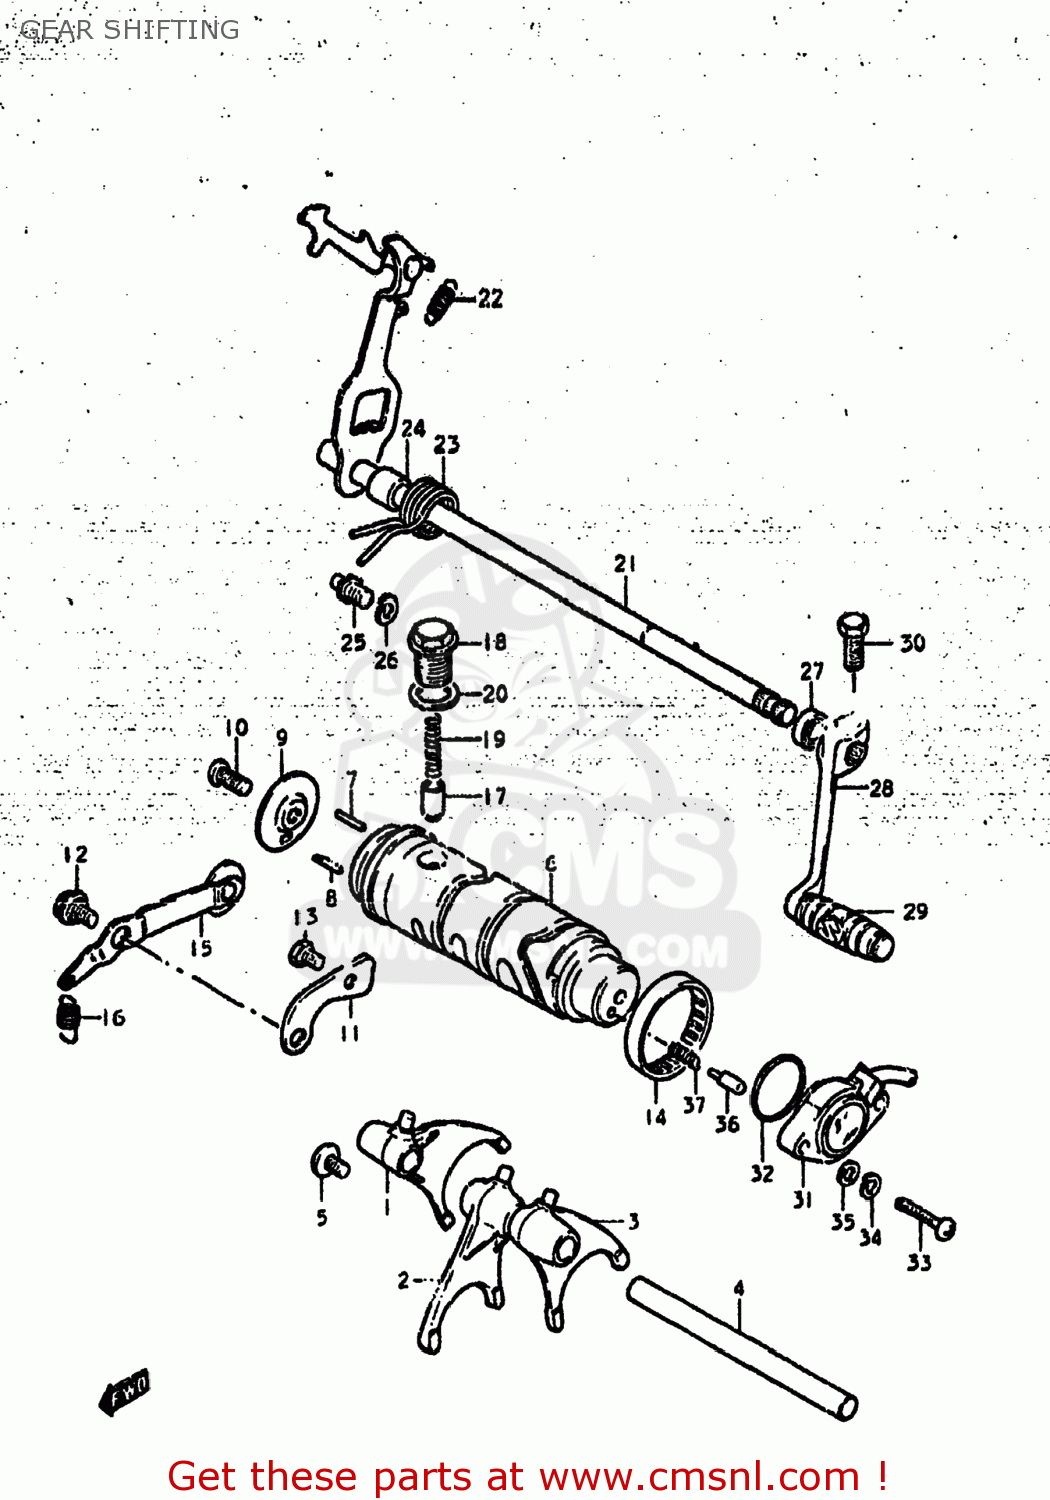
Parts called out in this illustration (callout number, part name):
1	FORK,GEAR SHIFT NO.1
2	FORK,GEAR SHIFT NO.2
3	FORK,GEAR SHIFT NO.2
4	SHAFT,GEAR SHIFT FORK
5	SCREW
6	CAM,GEAR SHIFT
7	PIN(4X18.5)
8	PIN
9	RETAINER,GEAR SHIFT CAM DR PIN
10	SCREW
11	GUIDE,GEAR SHIFTING CABLE
12	BOLT
13	BOLT
14	BEARING(40X47X12)
15	STOPPER,GEAR SHIFT CAM NO.1
16	SPRING
17	STOPPER,GEAR SHIFTING
18	BOLT,GEAR SHAFT CAM STOPPER
19	SPRING
20	GASKET(14X19.2X2) (NAS)
21	SHAFT,GEAR SHIFT
22	SPRING
23	SPRING
24	SPACER(12X20X15.3)
25	STOPPER,GEAR SHIFT CAM
26	WASHER
27	OIL SEAL
28	LEVER ASSY,GEAR SHIFT
29	RUBBER,GEAR SHIFT PEDAL
30	BOLT
31	TERMINAL BASE ASSY,GEAR SHIFT
32	O-RING (D:2.4 ID:26.2)
33	SCREW 5X20
34	LOCK WASHER
35	WASHER
36	PIN(5X15.5)
37	SPRING
